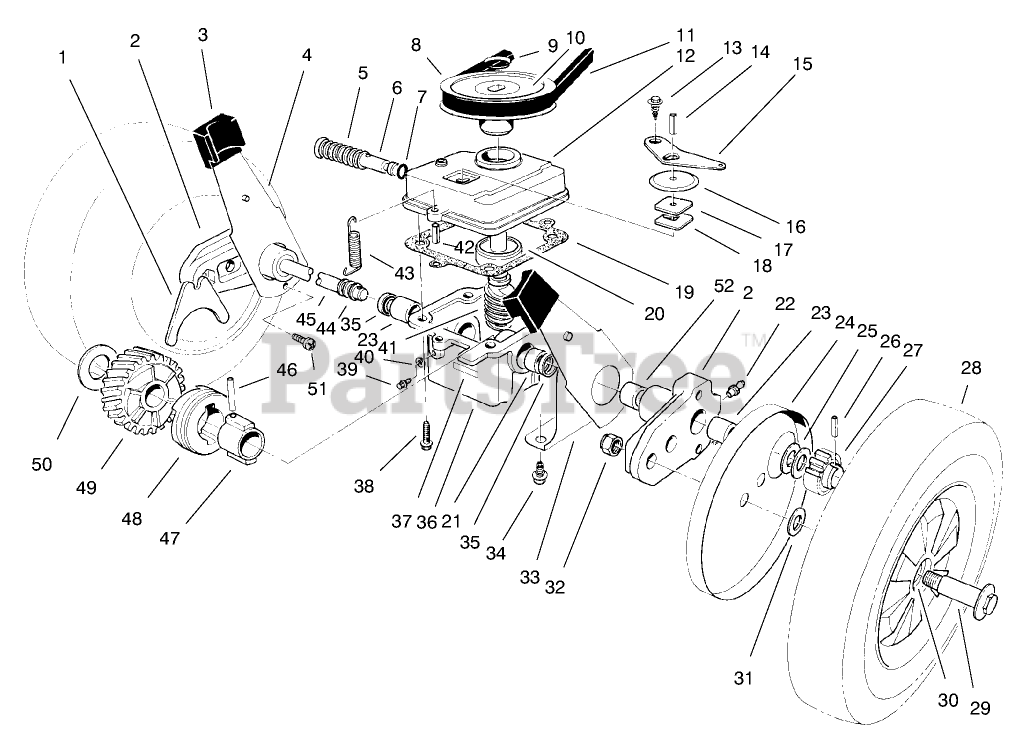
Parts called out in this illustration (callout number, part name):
1	SHIFTER FORK
2	PIVOT ARM ASM
3	KNOB-ARM
4	SPRING ARM ASSY-FRONT
5	SPRING
6	SHIFTER ROD
7	O-RING
8	PULLEY
10	DECAL
11	BELT-V
12	GEAR CASE COVER
13	SCREW-HWH
14	SPIROL PIN H D
15	SHIFTER ARM
16	DUST COVER
17	DUST FILTER
18	LATCH PLATE
19	GASKET
20	BEARING - BALL
21	BUSHING
22	FITTING-GREASE
23	BUSHING
26	COIL PIN
27	PINION GEAR 15T
28	WHL/GEAR/TIRE PKG
29	WHEEL BOLT
30	BUSHING
31	WASHER
32	NUT-LOCK
33	END CAP
34	SCREW-HWHTF
35	SEAL-OIL
36	GEAR CASE ASM
37	DECAL
38	SCREW-HWHTF
39	NYLON SCREW
40	FILL PLUG GASKET
41	WORM SHAFT & GEAR SET
42	3/16 X 1/2 ROLL PIN
43	TENSION SPRING
44	COVER-SHAFT, DRIVE
45	DRIVE SHAFT
46	COIL PIN
47	SLEEVE
48	CLUTCH JAW
49	Helical Gear
50	THRUST WASHER
51	SCREW
52	BUSHING
